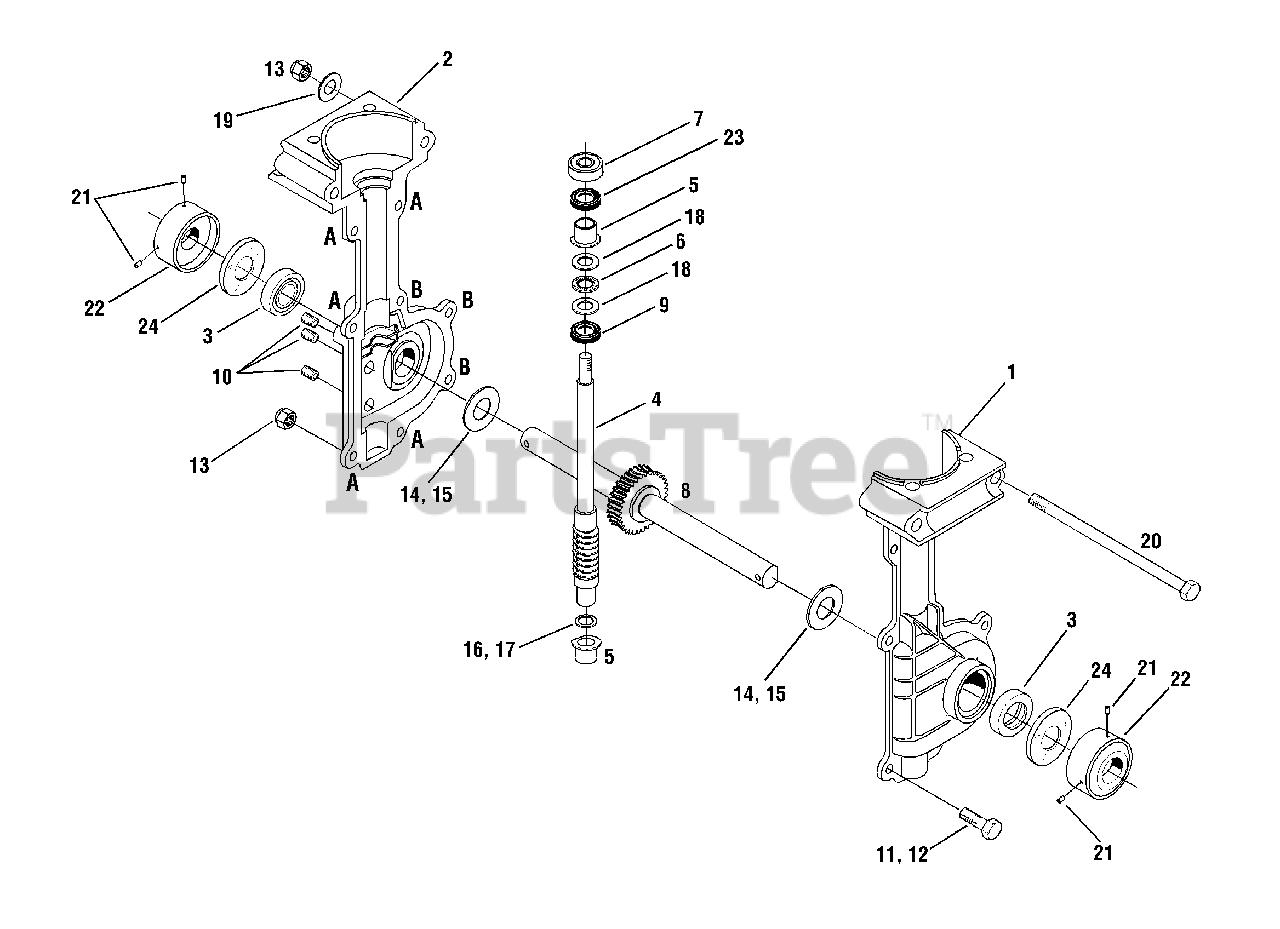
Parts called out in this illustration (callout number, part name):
1	Transmission Case - left-side
2	Transmission Case - right-side
3	Oil Seal
4	Worm Input Shaft Assembly
5	Input Bearing
6	Thrust Bearing
7	Ball Bearing
8	Shaft Assembly
9	Oil Seal, Input
10	Plug, 1/8
11	Hex Screw, 1/4-20 x 7/8 (five locations, identified as "A" on transmission case)
12	Hex Screw, 1/4-20 x 1 (three locations, identified as "B" on transmission case)
13	Locknut, Nyloc, 1/4-20
14	Thrust Washer, Output (.050")
15	Thrust Washer, Output (.040")
16	Thrust Washer, Input (.020")
17	Thrust Washer, Input (.035")
18	Thrust Washer
19	Flat Washer, 1/4
20	Hex Hd. Screw, 1/4-20 x 5
21	Set Screw, 1/4-28 x 3/8
22	Dust Cover
23	Oil Seal, Input
24	Felt Washer
